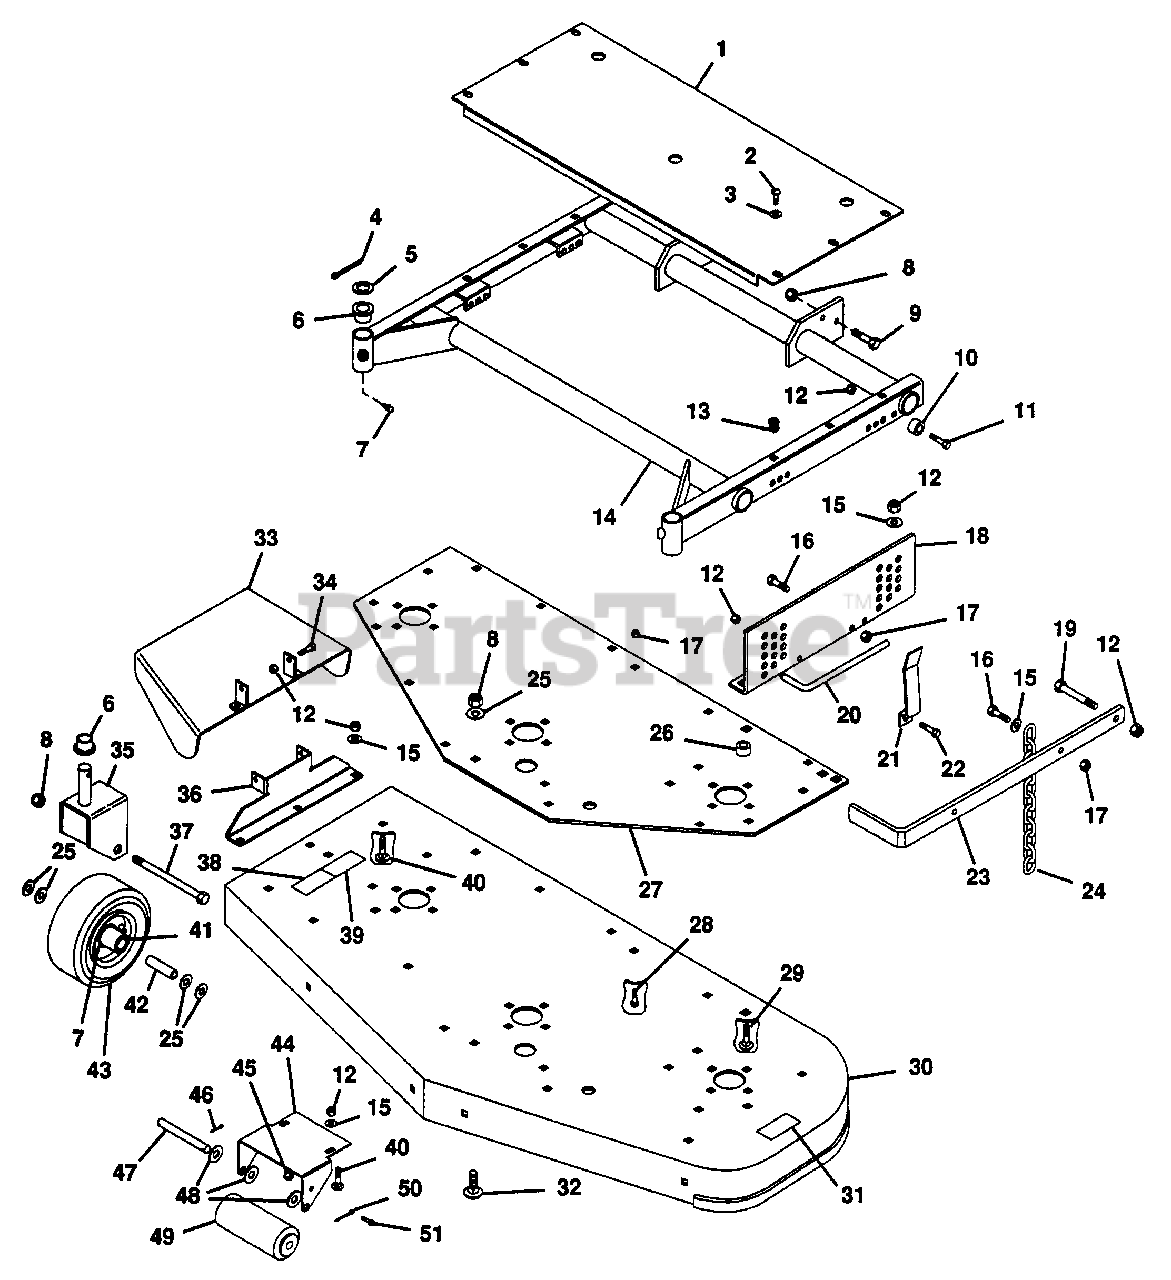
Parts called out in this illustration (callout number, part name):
1	Guard, Belt 60" PM Hand Series
2	Knob-Steering Lock
3	Washer-Flat-Steel .281 x .625 x .065
4	Pin-Cotter .188 x 1.625
5	Washer-Hardened-Thrust 1.002 x 1.552 x .030
6	Bushing-Flange 1.020 x 1.385 x .75 x 1.75
7	Fitting-Lube .25-28 x .256
8	Nut-Locking-Nylon .50-13 Grade 5
9	Bolt-Hex .50-13 x 1.50 Grade 5
10	Bushing .391 x .626 x .670
11	Bolt-Hex .38-16 x 1.50 Grade 5
12	Nut-Locking-Nylon .375-16 Grade 2
13	Grommet, Plastic
14	Weldment, Mower Frame
15	Washer-Flat-Steel .406 x .812 x .065
16	Bolt-Hex .31-18 x 1.00 Grade 5
17	Nut-Locking-Nylon .312-18 Grade 2
18	Bracket, Mower Support Left Hand
18	Bracket, Mower Support Right Hand
19	Bolt-Hex .38-16 x 2.0 Grade 5
20	Pin, Mower Locking
21	Spring, Pin
22	Bolt-Hex .38-16 x .75 Grade 5
23	Bar, Lift
24	Chain, Height Adjuster
25	Washer-Flat-Steel .531 x 1.250 x .100
26	Bushing .406 x .750 x .188
27	Plate, 60" Support
28	Bolt-Hex .31-18 x .75 Grade 5
29	Bolt-Round Head Square Neck .38-16 x 1.25
30	Weldment, 60" Mower
31	Decal, Danger Foot
32	Bolt-Round Head Square Neck .50-13 x 1.00
33	Weldment, Discharge Chute
34	Bolt-Hex .375-16 x 1.00 Grade 5
35	Weldment, Caster Fork
36	Bracket, Discharge
37	Bolt-Hex .50-13 x 5.50
38	Decal, Warning Eye
39	Decal, Danger Hand
40	Bolt-Round Head Square Neck .38-16 x 1.0
41	Bearing, Gauge Wheel
42	Spacer .532 x .748 x 3.34
43	Wheel 9 x 3.50
44	Bracket, Roller Right Hand
45	Nut-Locking-Nylon .250-20 Grade 2
46	Pin-Cotter .25 x 1.00
47	Shaft, Center Roller
48	Washer-Flat-Steel .656 x 1.312 x .095
49	Roller, Gage
50	Pin-Cotter .250 x 2.00
51	Bolt-Hex .25-20 x .75 Grade 5
